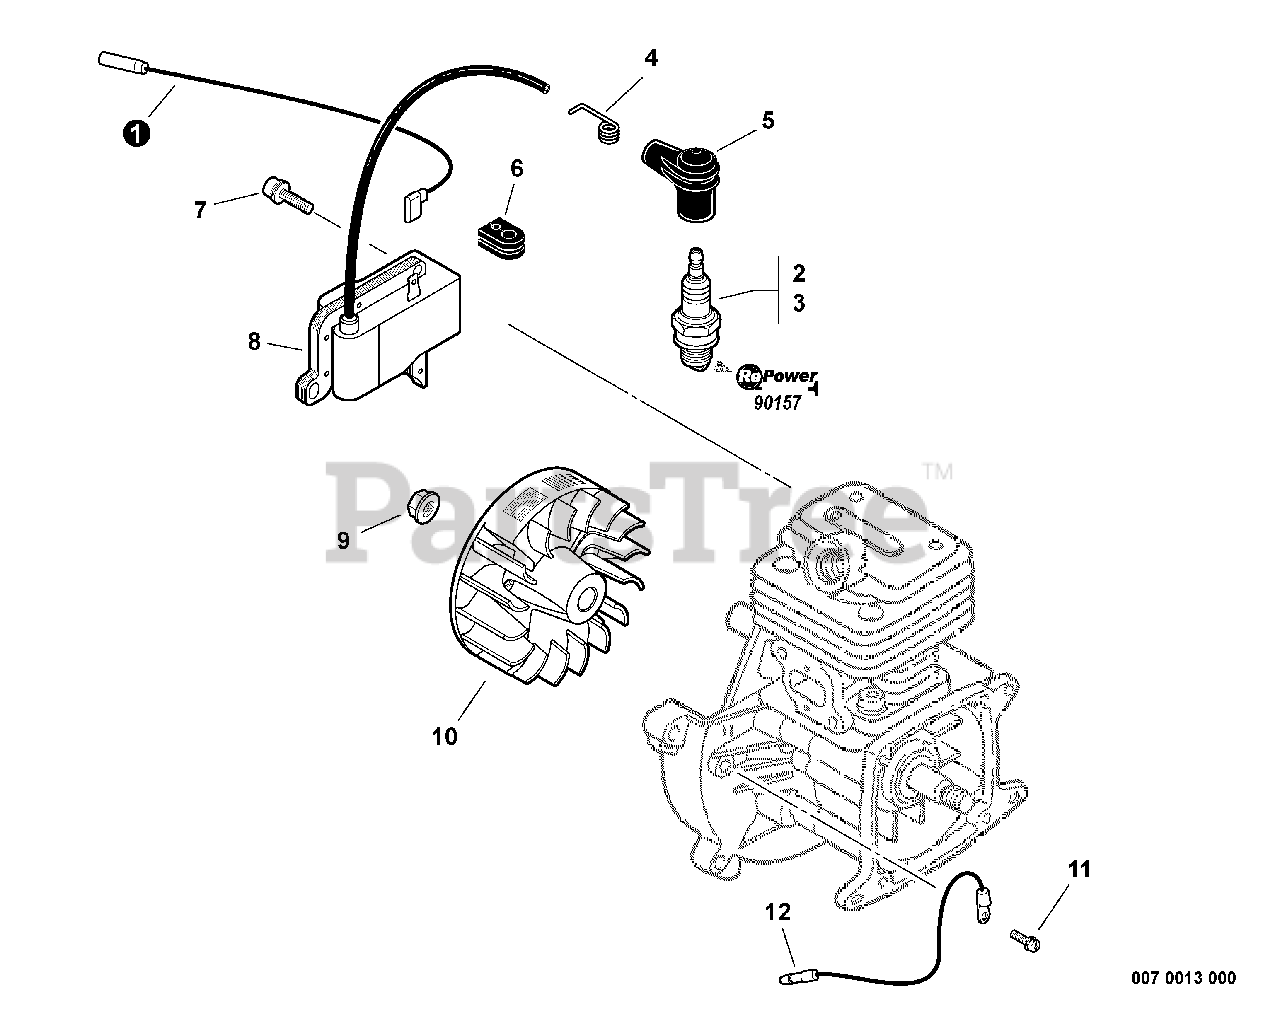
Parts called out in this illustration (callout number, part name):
1	LEAD - IGNITION 145 MM
2	SPARK PLUG - BPM-7Y
3	SPARK PLUG - BPMR7A
4	TERMINAL, SPARK PLUG
5	CAP, SPARK PLUG
7	BOLT 5×16
8	COIL, IGNITION
9	NUT, FLANGE M8
10	FLYWHEEL
11	SCREW 5×10
12	LEAD - GROUND
13	TUNE-UP KIT
